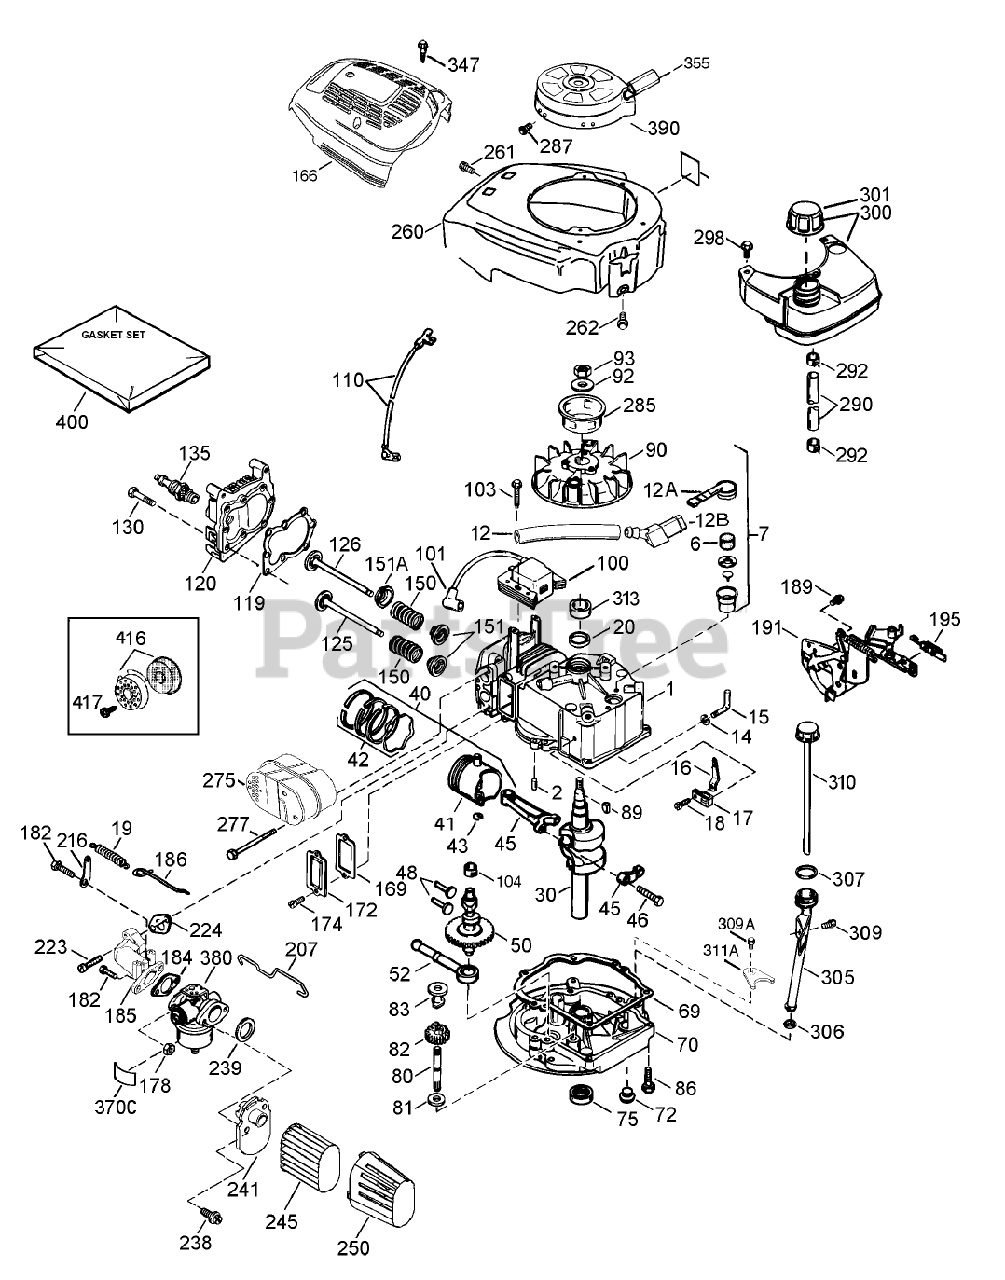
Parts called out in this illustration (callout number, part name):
1	Cylinder ASM
2	Pin-Dowel
6	Element-Breather
7	Breather ASM (Incl. Ref. #6 and 12A)
12	Tube-Breather
12A	Breather Cover and Tube (Incl. Ref. #12B)
12B	Elbow-Tube, Breather
14	Washer-Flat
15	Rod, Governor (Incl. No. 36)
16	Lever-Governor
17	Clamp-Lever, Governor
18	Screw (T-15, 8-32 x 19/64)
19	Spring-Extension
20	Seal-Oil
30	Crankshaft
40	Piston, Pin and Ring Set (Std.)
41	Piston and Pin ASM (Std.) (Incl. Ref. # 43)
42	FITTING - TANK 3/4"
43	Ring-Retaining, Piston Pin
45	Connecting Rod ASM (Incl. Ref. #46)
46	Bolt-Rod, Connecting
48	Lifter-Valve
50	Camshaft (Exhaust MCR) (Incl. Ref. #104)
52	Oil Pump ASM
69	Gasket-Flange, Mounting
70	Flange-Mounting (Incl. Ref. #72-83,306,309A 311A)
72	Plug-Drain, Oil
75	Seal-Oil
80	Shaft-Governor
81	Washer-Flat
82	Governor Gear ASM
83	Spool-Governor
86	Screw (1/4-20 x 1-1/4)
89	Key-Flywheel
90	Flywheel
92	Washer-Belleville
93	Nut-Flywheel
100	Ignition-State, Solid
101	Cover-Spark Plug
103	Screw (T-15, 10-24 x 15/16)
104	Bushing-Cam
110	Wire-Ground
119	Gasket-Cylinder Head
120	Head-Cylinder
125	Valve-Exhaust (1/32in OS) (Incl. 151)
125	Valve-Exhaust (Std.) (Incl. Ref. #151)
126	Valve-Intake (Std.) (Incl. Ref. #151 and 151A)
130	Screw (5/16-18x1-1/2)
135	Spark Plug-Resistor (R J19 L M)
150	Spring-Valve
151	Cap-Valve, Spring
151A	BEARING - TRANS
166	Shroud-Engine
169	Gasket-Cover, Valve
172	Cover-Valve
174	Screw (10-24 x 9/16)
178	Nut and Lock Washer (1/4-28)
184	Gasket
185	Pipe-Intake
186	Link-Governor
189	Screw (1/4-20 x 3/8)
191	Bracket-S.E. Brake (Incl. Ref. #195)
195	Terminal
207	Link-Throttle
216	Lever-Adjusting, R P M
223	Screw (1/4-20 x 1)
224	Gasket-Pipe, Intake
238	Screw (10-32 x 49/64)
239	Gasket-Cleaner, Air
241	Collar-Cleaner, Air
245	Filter-Cleaner, Air (Paper)
250	Cover-Cleaner, Air
260	Blower Housing
261	Screw (10-24 x 9/16)
262	Screw (1/4-20 x 1/2)
275	Muffler
277	Screw (1/4-20 x 2-9/32)
285	Cup-Starter
287	Screw (8-32 x 21/64)
290	Line-Fuel (8.62)
292	Clamp-Line, Fuel
300	Fuel Tank (Incl. Ref. #292 and 301)
301	Cap-Fuel
305	Oil Fill Tube (Incl. 306)
306	O-Ring
307	O-Ring
309	Screw (10-32 x 1/2)
309A	Screw (10-24 x 3/4)
310	Dipstick
311A	Bracket-Holddown
313	Spacer
347	Screw (10-32 x 27/32)
370C	Decal-Primer
370D	Decal-Warning
380	Carburetor (Incl. Ref. #184 of Engine Parts List)
390	Rewind Starter ASM
400	Gasket Set
416	Spark Arrestor Kit (Incl. 417)(Optional)
417	Screw (8-32 x 3/8)
